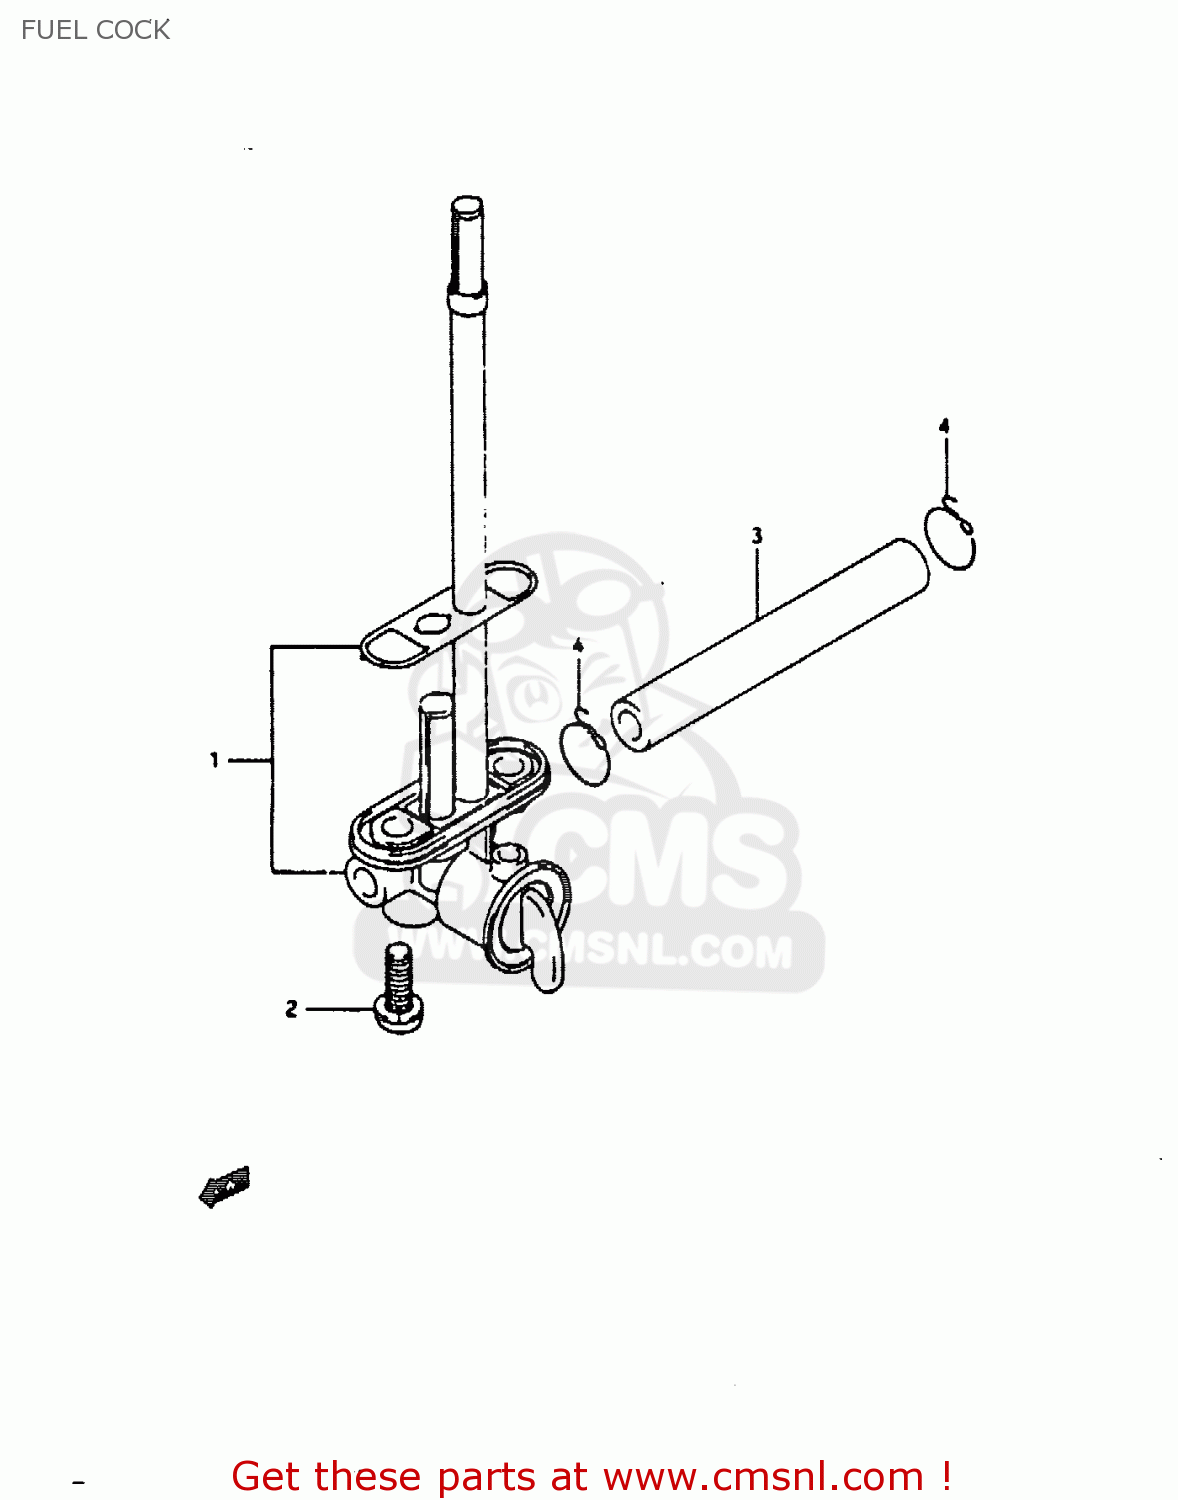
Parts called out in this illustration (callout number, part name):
1	COCK ASSY,FUEL
2	SCREW
3	HOSE,FUEL
4	CLIP
